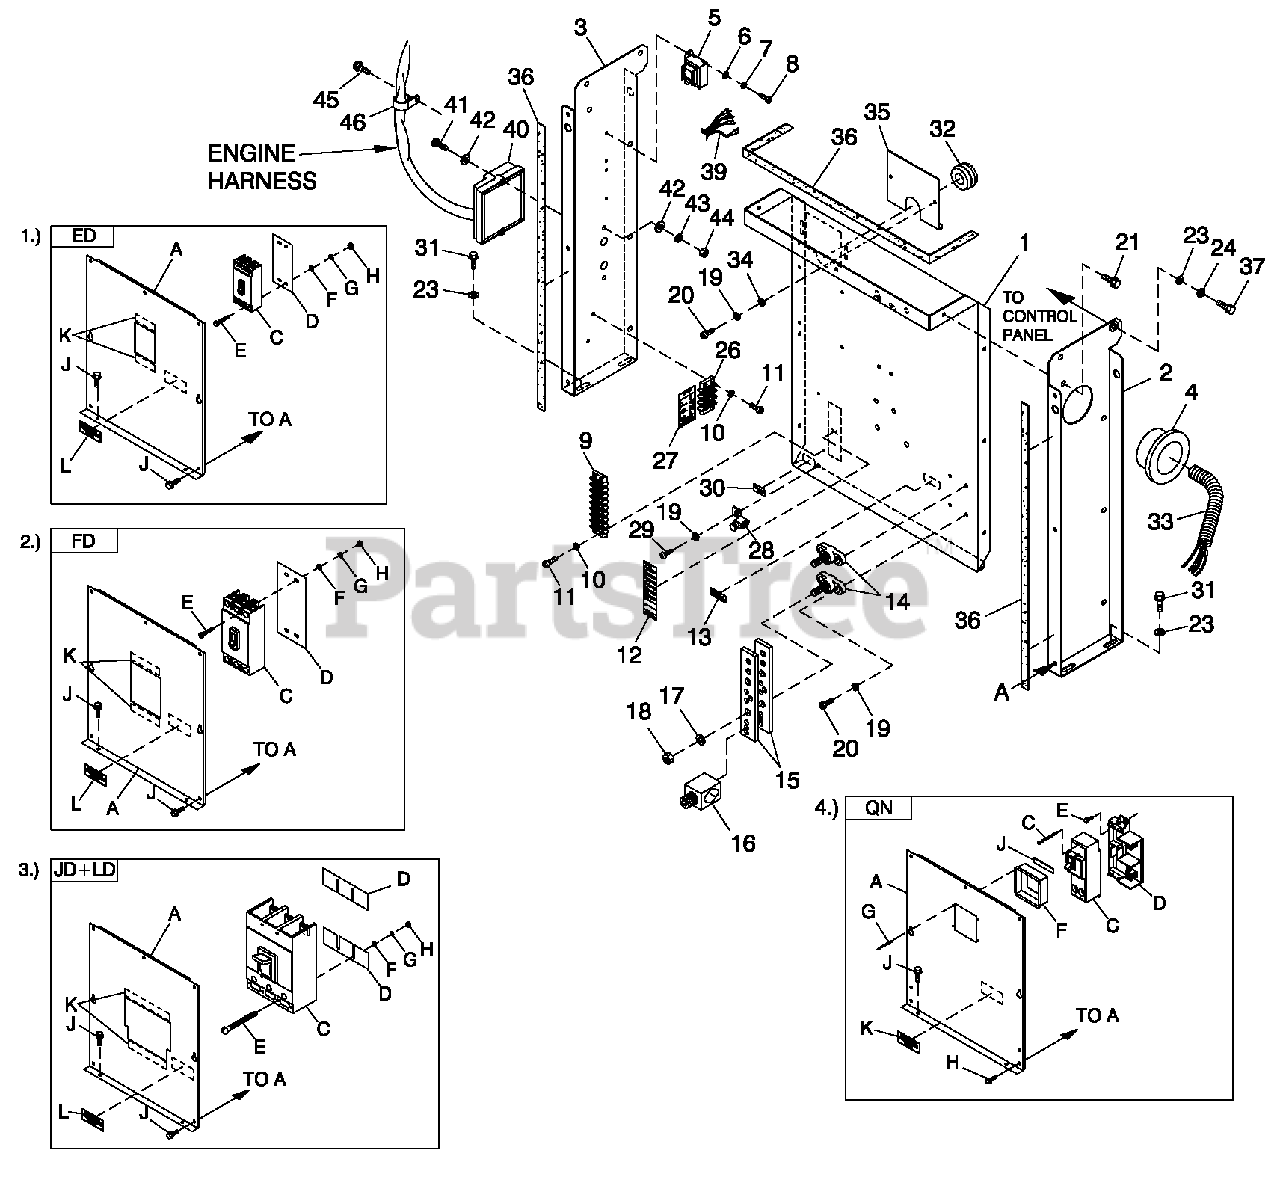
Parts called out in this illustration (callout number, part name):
1	PAN CBCONN BOX
1	UL CIRCUIT BREAKER(ED)
2	STAND RH CONTROL
2	UL CIRCUIT BREAKER (ED)
3	STAND LH CONTROL
3	UL CIRCUIT BREAKER (JD+LD
4	BUSHING SNAP SB-2.5-31
4	UL CIRCUIT BREAKER (QN)
5	XFMR DUAL 120V/16V (FOR 120/240V & 277/480V UNITS)
6	WASHERFLAT M4
7	WASHERLOCK #8-M4
8	SCREW PHTT M4-0.7 X10ZYC
9	BLOCKTE RM 20A8 X 6 X1100V
10	WASHERLOCK #6
11	SCREW PHTT #6-32 X1/2ZYC
12	DECAL UT L SENSE/CUST CONN
13	DECAL ^U T R A L
14	JUNCTION BLOCK 3/8-16
15	BUS BAR NEUTRAL BLOCK 390
16	LUG SLDLSS 600/250-1/0 X 1/4-28
17	WASHERLOCK 3/8
18	NUT H E X 3/8-16 STEEL
19	WASHERLOCK M5
20	SCREW PHTT M5-0.8 X16ZYC
21	SCREW THFM6-1X 16N WAZ/JS
23	WASHERFLAT 1/4-M6ZINC
24	WASHERLOCK M6-1/4
26	BLOCKTE RM 20A6 X 3 X1100V
27	DECAL CUST CONN 120V UTILITY
28	LUG SLDLSS#6-14X13/64 CU
29	SCREW HHTT #10-32 X 3/8C Z
30	DECAL GROUND LUG
31	SCREW HHTT M6-1.0 X16ZYC
32	GROMMET 1.25X .25 X .75
33	CONDUIT FLEX 2.0' ID (36" LG)
34	WASHERFLAT M5
35	PLATE WIRE SNGLGALV
36	TAPE ELEC 1/2 FOAM (AS REQ'Q
37	SCREW HHC M6-1.0X 16G8.8
39	HARNESS, TRANSFORMER ADAPTER
40	ASSY ENCLOSURE PCB 4.2L IGN MD
41	SCREW PPHM #10/32X2
42	WASHERFLAT #1 0ZINC
43	WASHERLOCK #10
44	NUT HEX#10-32 STEEL
45	SCREW THF M6-1 X 1 6 N WAZ/JS
46	CLAMP V INYL 1.06 X .406 Z
47	SEALWEATHER.45' DIA
A	COVERED CB SHORT STND
C	CB0050A3P 480V S ED4 LL
D	INSULATOR CBS (ED-3 P)
E	SCREW RHM #10-32X4-1/2
F	WASHERFLAT #1 0ZINC
G	WASHERLOCK #10
H	NUT HEX#10-32 STEEL
J	SCREW THF M 6-1 X 16 NWAZ/JS
K	TAPE ELEC 1/2 FOAM (AS REQ'D)
L	DECAL CUSTOMER CONNECT INSIDE
A	COVERCBCONN BOX
C	CB0150A3P 600VS FD6LL
D	INSULATOR CB FD FRAME 30ML
E	SCREW SHC1/4-20X 4.5 G8.8NZ
F	WASHERFLAT 1/4-M6ZINC
G	WASHERI OCK MR. 1/4
H	NUT HEX 1/4-20STEEL
J	SCREW THF M6-1 X 1 6 NWAZ/JS
L	DECAL CUSTOMERCONNECT INSIDE
A	COVER JD/LDCB SHRT STAND
C	CB 0300A3P600V SJD6 LL
D	INSULATOR CIRCUIT BR. JD/LD
E	SCREW RHM 1/4-20 X 3
F	WASHER FLAT 1/4-M6 ZINC
G	WASHER LOCK M6-1/4
A	COVER QN FRMCB
C	CB0150A2P240V SQN2 LL
D	BASE, QNCIRCUIT BREAKER
E	SCREW HHTT M5-0.8X10BP
F	COVER QNCBDISH
G	RIVET POP .125 X .275 SS
H	SCREW THF M 6-1X16 N WAZ/JS
J	TAPE ELEC 1/2 FOAM (AS REQ'D)
K	DECAL CUSTOMERCONNECT INSIDE
